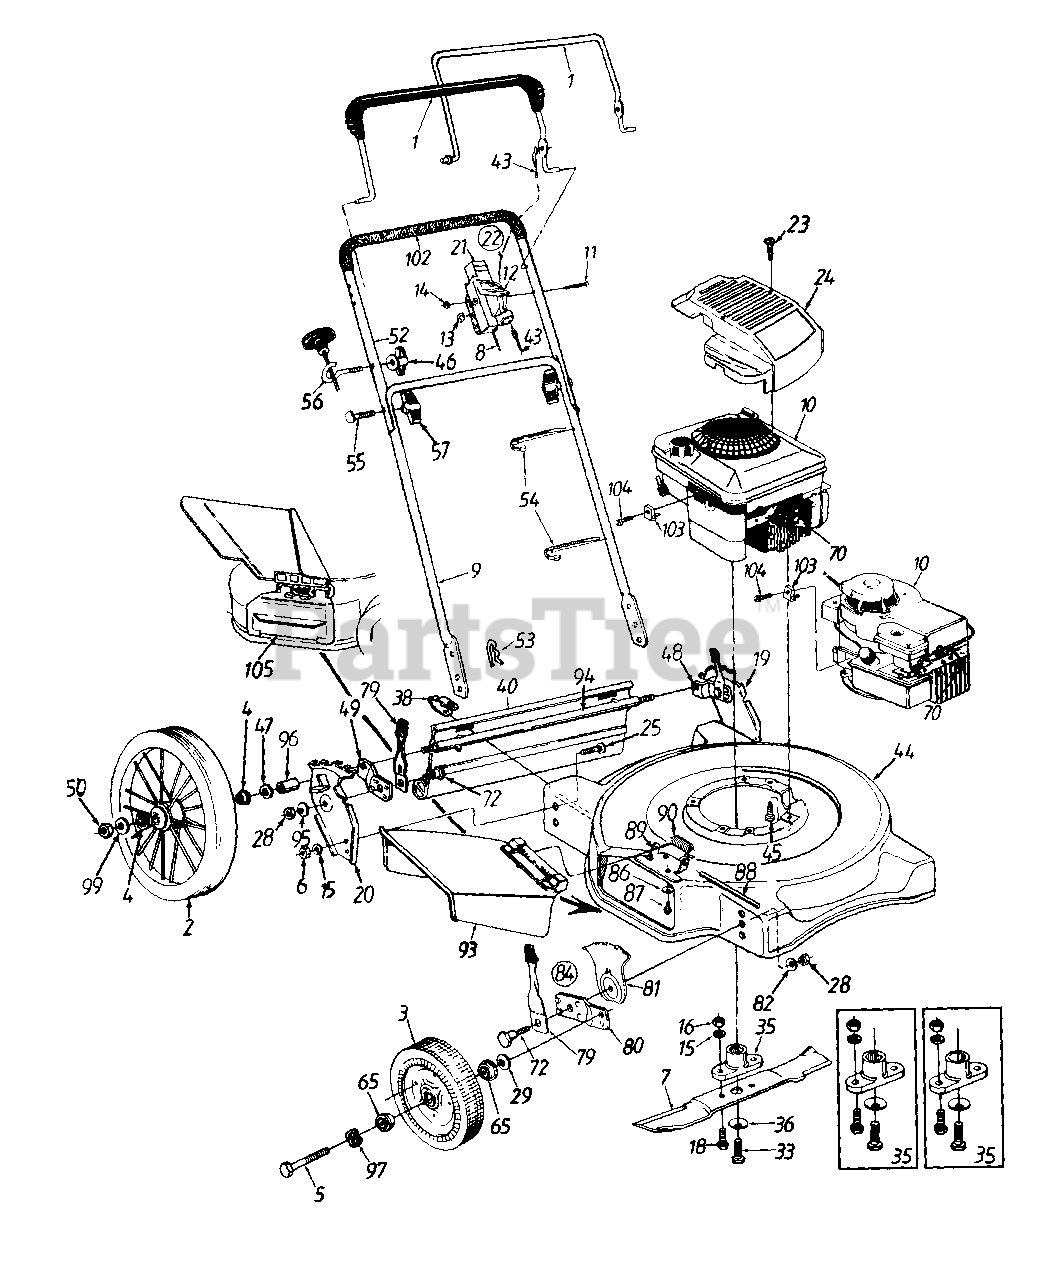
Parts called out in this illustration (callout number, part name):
2	16" Wheel Ass'y.
3	Front Wheel Ass'y.
4	Bearing 1/2" I D.
5	Front Axle Bolt
6	Hex Nut 3/8-24 Thd. (Gr. 8)
7	22" Blade
8	Throttle Control Wire - 51" (B&S)
10	Engine
11	Oval C-Sunk Mach. Scr.
12	Throttle Lever
13	Spr. Wash .66" I.D.
14	Hex L-Nut 1/4-20 Thd.
15	L-Wash. 3/8" I.D."
16	Hex Nut 3/8-24 Thd.
18	Hex Bolt 3/8-24 x 1.0" Lg.
22	Throttle Box Comp.
23	Hi-Lo Scr. #10 x 1.25" Lg.
24	XTE Black Shroud
25	Ribbed Neck Bolt 3/8-24 x .80"
28	Hex Nut 3/8-16 Thd.
29	Bell-Wash .400" I.D. x .88"
33	Hex Bolt 3/8-24 x 1.5" Lg.
35	Blade Adapter Kit (Keyed)
36	Bell-Wash .39" I.D.
40	Rear Flap Ass'y.
43	Control Cable - 39" (B&S)
46	Handle Knob 1/4-20 Thd.
47	Wave Wash .51" I.D.
48	Small Pivot Bar - L.H.
49	Small Pivot Bar - R.H.
50	Hex Jam Nut 3/8-16 Thd.
54	Cable Tie
55	Curved Hd. Bolt 5/16-18 x 2" Lg.
56	Rope Guide
57	Hand Knob
65	Bearing
70	Spark Plug Boot
72	Shoulder Bolt .50" Dia.
79	Spring Lever Ass'y. w/Knob
81	Height Adj. Plate
82	Bell-Wash .39" I.D. x 1.38"
86	Bell-Wash .285" I.D. x .75"
87	Hex Wash. Hd. Tap Scr. 1/4-20 x .5" Lg.
88	Hinge Pin
89	Adapter Plate
90	Torsion Spring
93	Chute Deflector Ass'y. Comp.
94	Rear Axle
95	Bell-Wash .39" I.D. x 1.13"
96	Spacer.55" I.D. x .75"
97	Wave Washer.51" I.D.
99	Fl-Wash .406" I.D. x .81"
102	Foam Grip
103	Casing Clamp (B&S)
104	Hex Wash. Hd. Tap Scr. #10-32 x .62" Lg. (B&S)
105	Mulching Baffle
